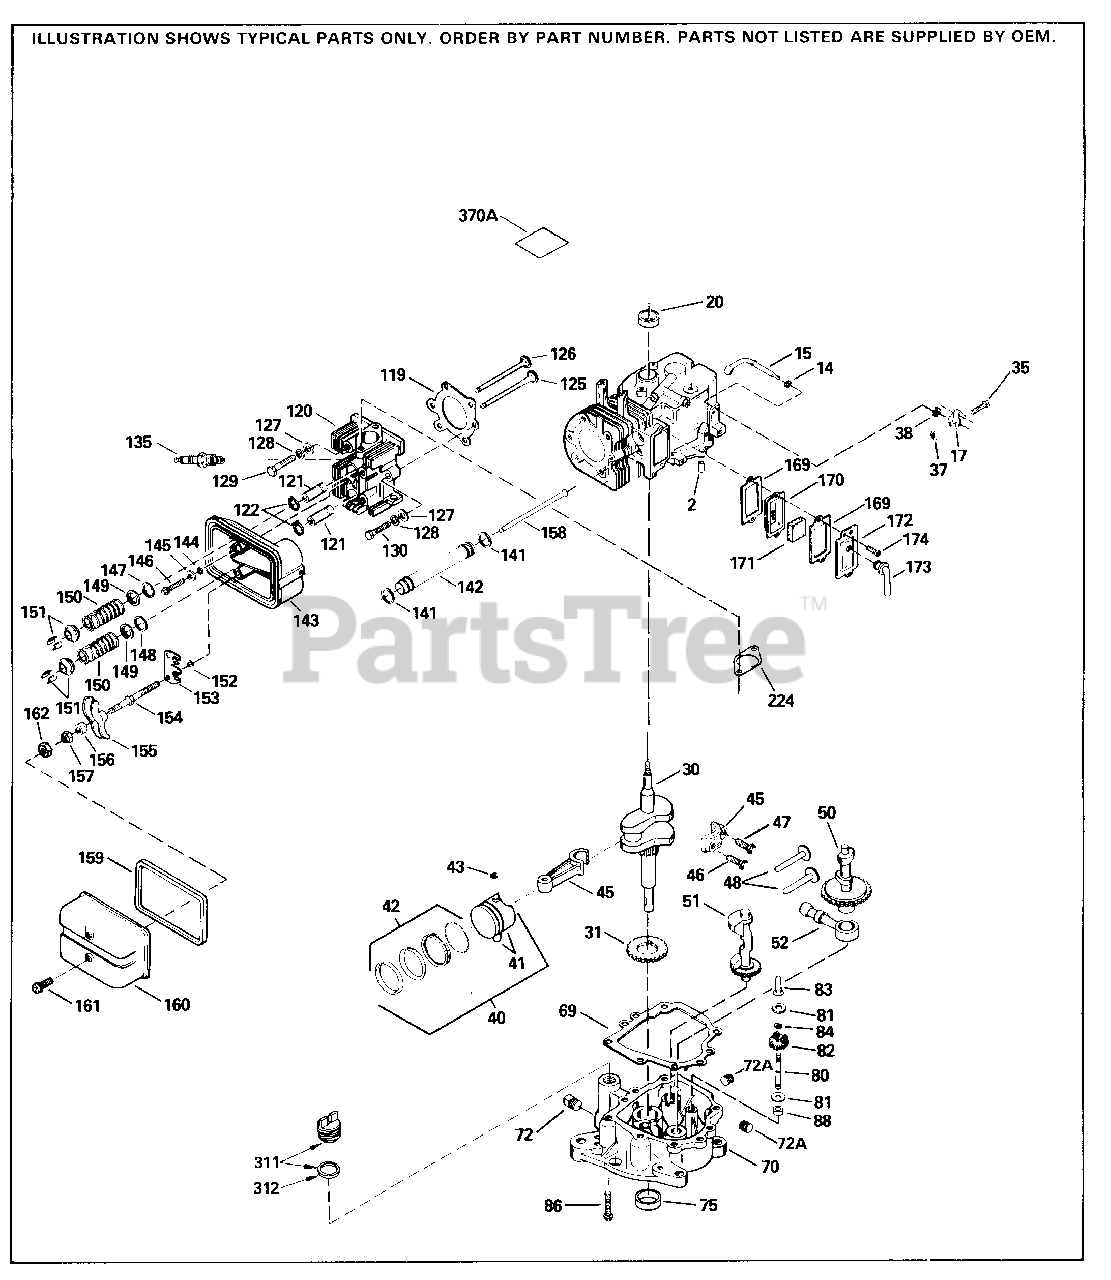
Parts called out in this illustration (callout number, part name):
1	"Cylinder (Incl. 2 & 20) 3-5/16" Bore
2	Dowel Pin
14	Flat Washer
15	Governor Rod
17	Governor Lever Clamp
20	Oil Seal
30	Crankshaft (counterbalance)
31	Counterbalance Gear
35	Screw, 10-32 x 3/4"
37	Lock Nut, 10-32
38	Retaining Ring
40	Piston, Pin & Ring Set (Std.)" Bore)
40	Piston, Pin & Ring Set (.010" OS)
40	Piston, Pin & Ring Set (.020" OS)
41	Piston & Pin Ass'y. (Std.) (Incl. 43) 3-5/16")
41	Piston & Pin Ass'y. (.010" OS) Incl. 43
41	Piston & Pin Ass'y. (.020" OS) Incl. 43
42	Ring Set (Std.) (3-5/16")
42	Ring Set (.010" OS)
42	Ring Set (.020" OS)
43	Piston Pin Retaining Ring
45	Connecting Rod Ass'y. (Incl. 46 & 47)
46	Connecting Rod Bolt
47	Connecting Rod Bolt
48	Valve Lifter
50	Camshaft (MCR)
51	Counterbalance Weight Assy.
52	Oil Pump Assy.
69	Mounting Flange Gasket
70	Mounting Flange (Incl. 72, 72A, 75 & 80)
72	Pipe Plug (1/8-27 sq. hd.)
72	Pipe Plug (3/8-18 sq. hd.)
72A	Oil Drain Plug (3/8-18)
75	Oil Seal
80	Governor Shaft
81	WASHER
82	Governor Gear Assembly
83	Governor Spool
84	Retaining Ring
86	Powerlok Screw, 1/4-20 x 1-3/16"
88	Governor Gear Spacer
119	Cylinder Head Gasket
120	Cylinder Head
121	Exhaust Valve Guide
122	Retaining Ring
125	Exhaust Valve (Std.)
125	Exhaust Valve (1/32" OS)
126	Intake Valve (Std.)
126	Intake Valve (1/32" OS)
127	Flat Washer
128	Belleville Spring Washer
129	Screw, 5/16-18 x 1-3/8"
130	Screw, 5/16-18 x 1-3/4"
141	"O" Ring
142	Push Rod Tube
143	Rocker Arm Housing
144	"O" Ring
145	Flat Washer
146	Screw, 1/4-20 x 29/32"
147	"O" Ring (Intake)
148	"O" Ring (Exhaust)
149	Valve Spring Cap
150	Valve Spring
151	Valve Spring Cap & Keeper
152	"O" Ring
153	Push Rod Guide
154	Rocker Arm Stud
155	Rocker Arm
156	Rocker Arm Bearing
157	Lock Nut (Incl. 162)
158	Push Rod
159	"O" Ring (Valve Cover)(Incl. 161)
160	Rocker Arm Housing
161	Screw, Torx T-20, 8-32 x 1/2 "
162	Hex Jam Nut
169	Valve Cover Gasket
170	Breather Body
171	Breather Element
172	Valve Cover
173	Breather Tube
174	Screw, 10-24 x 1/2"
224	Intake Gasket
311	Oil Fill Plug (Incl. 312) also availa ble in Packaged Part #740079
312	Oil Fill Plug Gasket
370A	Lubrication Decal
